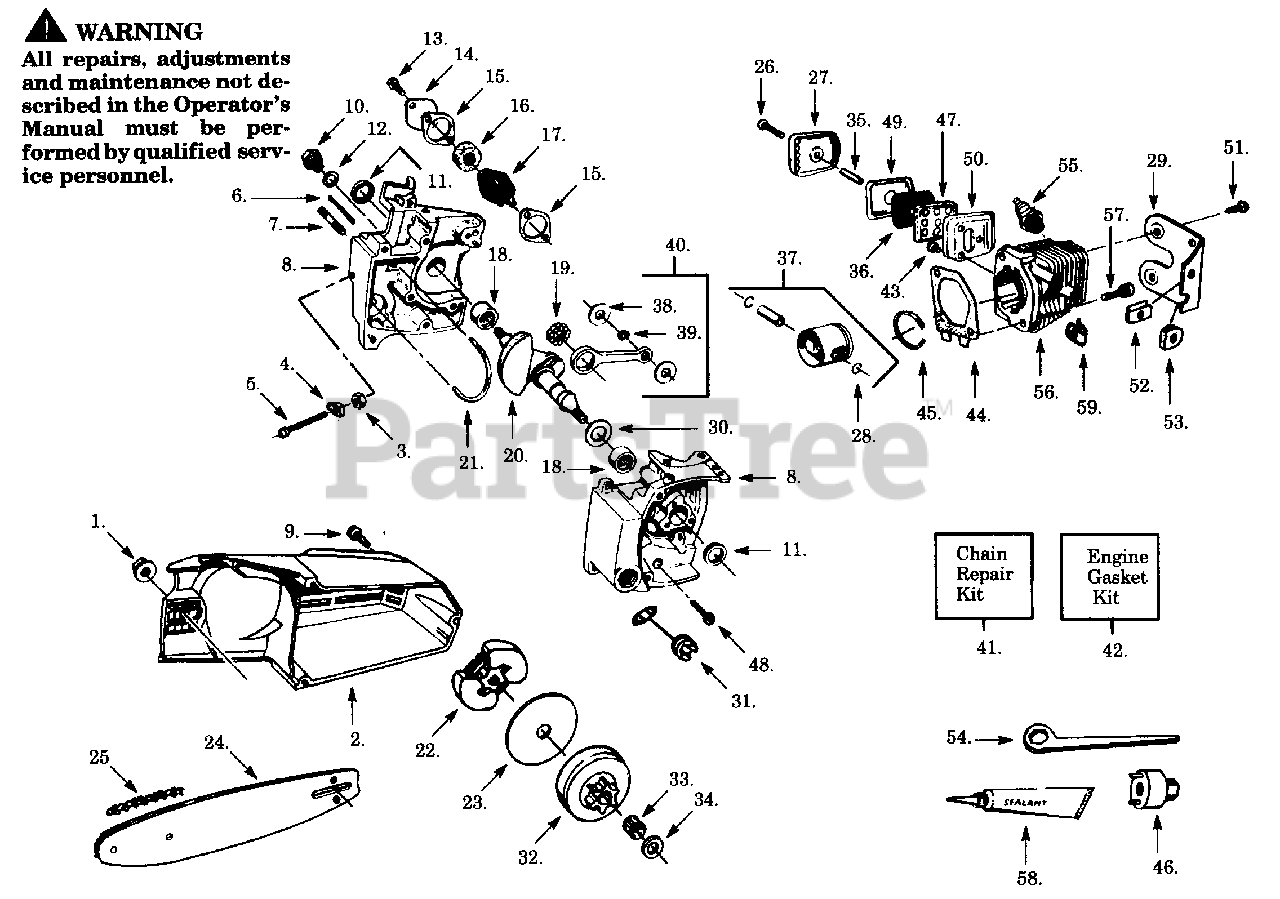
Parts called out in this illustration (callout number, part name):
1	Bar Mounting Nut
2	Bar Clamp
4	Bar Adjust Pin
5	Screw
6	Oil Tank Vent Pin
7	Bar Mounting Stud
8	Crankcase Ass'y.
10	Check Valve Kit
11	Crankshaft Seal
12	Check Valve Gasket
15	Metering Body Gasket
16	Oil Filter (Foam)
17	Oil Pump Ass'y.
18	Crankshaft Bearing
19	Roller Bearing
20	Crankshaft
21	Oil Discharge Line
22	Clutch Ass'y. Kit
23	Clutch Washer Kit
24	Guide Bar, Model 2100-14"
24	Guide Bar, Model 2100 & 2400 G.SAW- 16"
24	Guide Bar, Model 2400 G.SAW-18"
25	Chain, Model 2100-14"
25	Chain, Model 2100 & 2400 G.SAW - 16"
25	Chain, Model 2400 G.SAW-18"
27	Muffler Cover
28	Piston Pin Retainer
29	Rear Mount Bracket
30	Thrust Washer
31	Oil Cap Ass'y.
32	Clutch Drum
33	Clutch Bearing
34	Clutch Spacer-Inside
35	Muffler Spacer
36	Muffler Screen
37	Piston Kit
39	Bearing Rod Top
40	Connecting Rod Assy
41	Chain Repair Kit
42	Engine Gasket Kit (*Indicates Contents)
44	Cylinder Gasket
45	Piston Ring, Model 2100
45	Piston Ring, Model 2400 G.SAW
46	Clutch Tool
47	Muffler Baffle-Inner
49	Muffler Baffle-Outer
50	Muffler Body
52	Speed Nut
54	Bar Wrench
55	Spark Plug
56	Cylinder, Model 2100
56	Cylinder, Model 2400 G.SAW
58	Crankcase Sealant
59	Wire Clip
